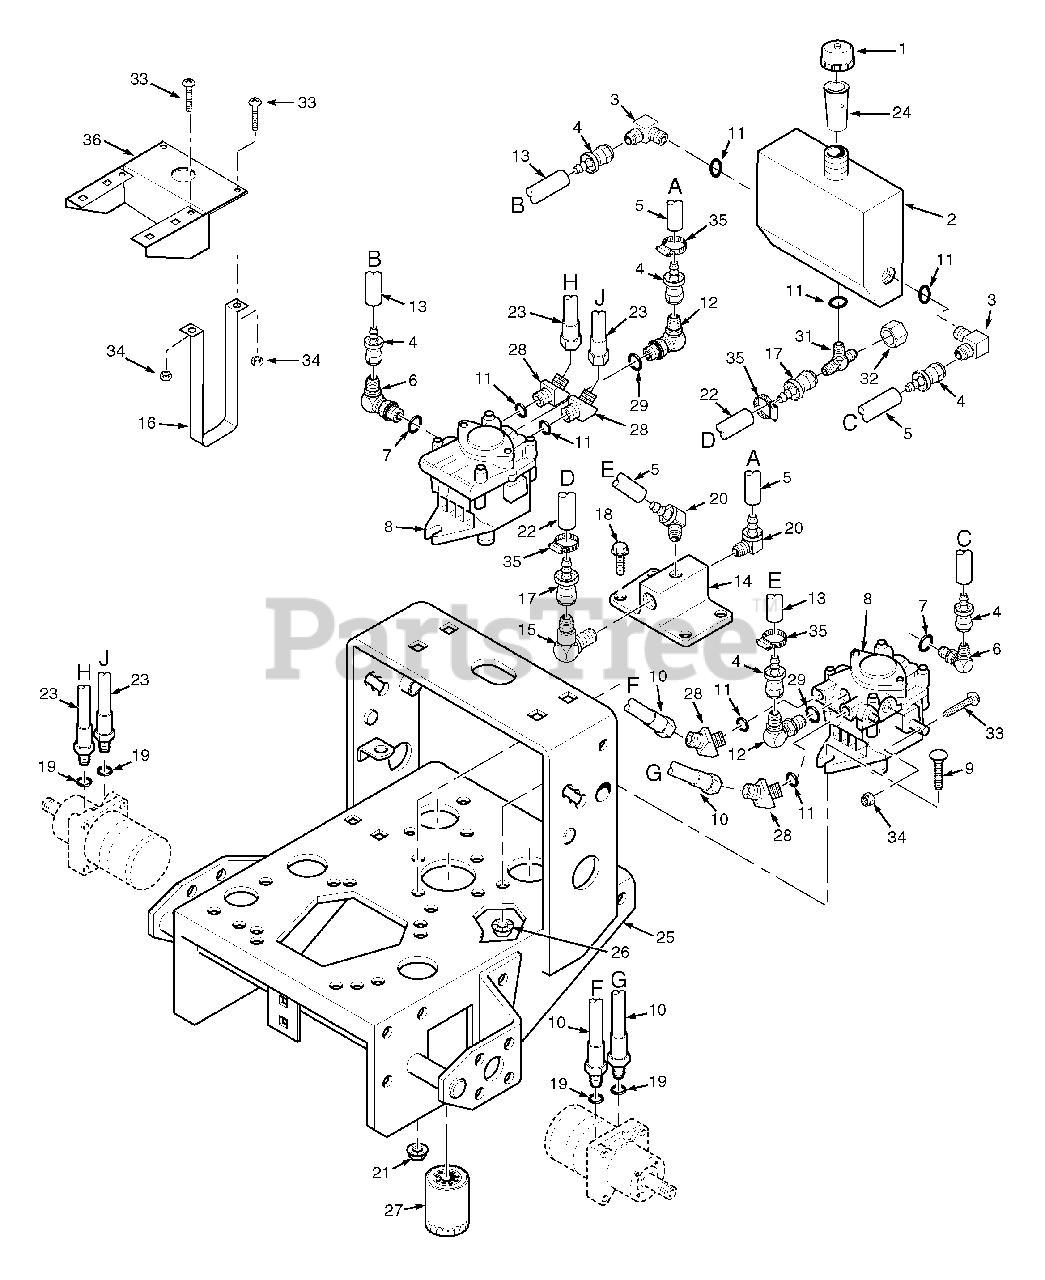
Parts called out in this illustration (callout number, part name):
1	Cap, Oil Reservoir
2	Oil Reservoir
3	Elbow, 90 deg. 7/16-20 x 9/16-18
4	Coupling, 7/16-20 SAE Flare Swivel to 1/4" Hose Push On
5	Hose, 1/4" ID - 7" Long
6	Elbow, 90 deg. 7/16-20 JIC to 9/16-18 "O" Ring
7	O-Ring
8	Pump, Hydro-Gear BDP-10L117
9	Bolt, Carriage, 3/8-16 x 1.25"
10	Hose, Pump to Wheel Motor
11	O-Ring
12	Elbow, 90 deg., 1/2 NPT
13	Hose, 1/4" ID - 5" Long
14	Oil Filter Base
15	Elbow, 90 deg. 1/2" NPT
16	Strap, Hydraulic Tank
17	Coupling, 3/4-16 SAE to 1/2" Hose Push On
18	Capscrew, 5/16-18 x .75" Serr. Flange
19	O-Ring
20	Elbow, 90 deg. Male 1/4 NPT to 1/4 Hose Push On
21	Nut, 5/16-18 Serr. Flange
22	Hose, Formed 1/2" ID
23	Hose, Pump to Wheel Motor
24	Tube, Filler Neck
25	Engine Deck (16" Wide) W/Decals - Small Frame
26	Nut, 3/8-16 Serr. Flange
27	Oil Filter
28	Elbow, 45 Deg.-3/4-16 JIC Male x Male 3/4-16 O-Ring
29	O-Ring
30	Coupling, 3/8 Pipe to 1/2 Push-on
31	T-Fitting, 1/2 (3/4-16)
32	Cap, 3/4-16
33	Screw, 1/4-20 x 2.0" Round Head Phillips
34	Nut, 1/4-20
35	Clamp,.87 Max Dia.
36	Bracket, Hydraulic Tank
